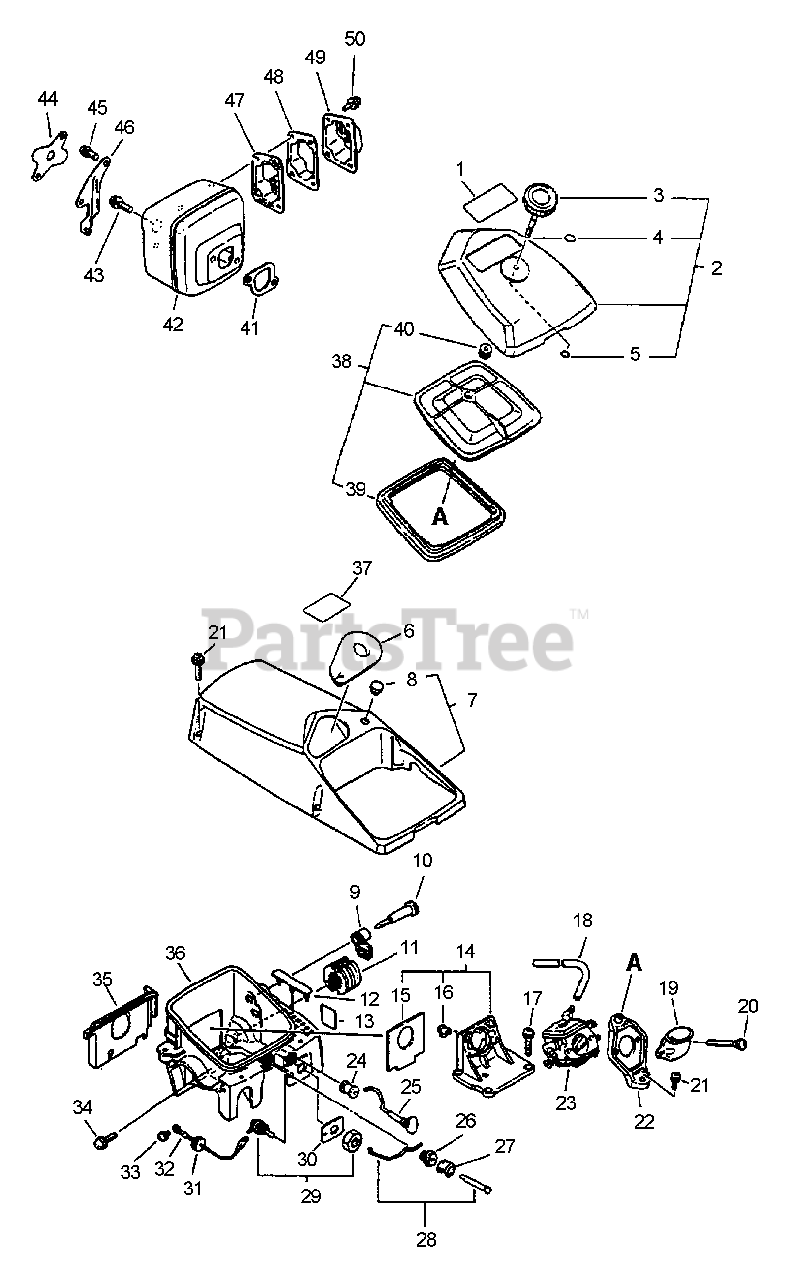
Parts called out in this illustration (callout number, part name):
1	LABEL - MODEL QV-8000
2	AIR FILTER COVER ASSY
3	THUMBSCREW
4	O-RING - 10
5	O-RING - 3
6	PLATE, GUIDE
7	ENGINE COVER KIT - GRAY
10	SCREW, IDLE ADJUST
12	PLUG
14	INSULATOR, INTAKE
15	SEAL, DUST
16	NUT
17	SCREW - 5X25
18	PIPE - IMPULSE
19	PLATE, PREVENT
20	SCREW - 5X55
21	SCREW - 5X14
22	BRACKET, AIR CLEANER
23	CARBURETOR
25	ROD, CHOKE
26	GUIDE, THROTTLE ROD
28	ROD, THROTTLE
29	IGNITION SWITCH ASSY
30	LABEL - STOP
32	LEAD - GROUND
33	SCREW - 4X8
34	SCREW - 4X8
35	PLATE, GUIDE
36	CASE, CARBURETOR
37	LABEL - KICK BACK
38	FILTER, AIR
41	GASKET, EXHAUST
43	SCREW - 6X20
44	COVER, MUFFLER
45	SCREW - 5X14
46	BRACKET, MUFFLER
47	SCREEN, SPARK ARRESTOR
48	GUIDE, EXHAUST - INNER
49	GUIDE, EXHAUST - OUTER
50	SCREW - 4X10
